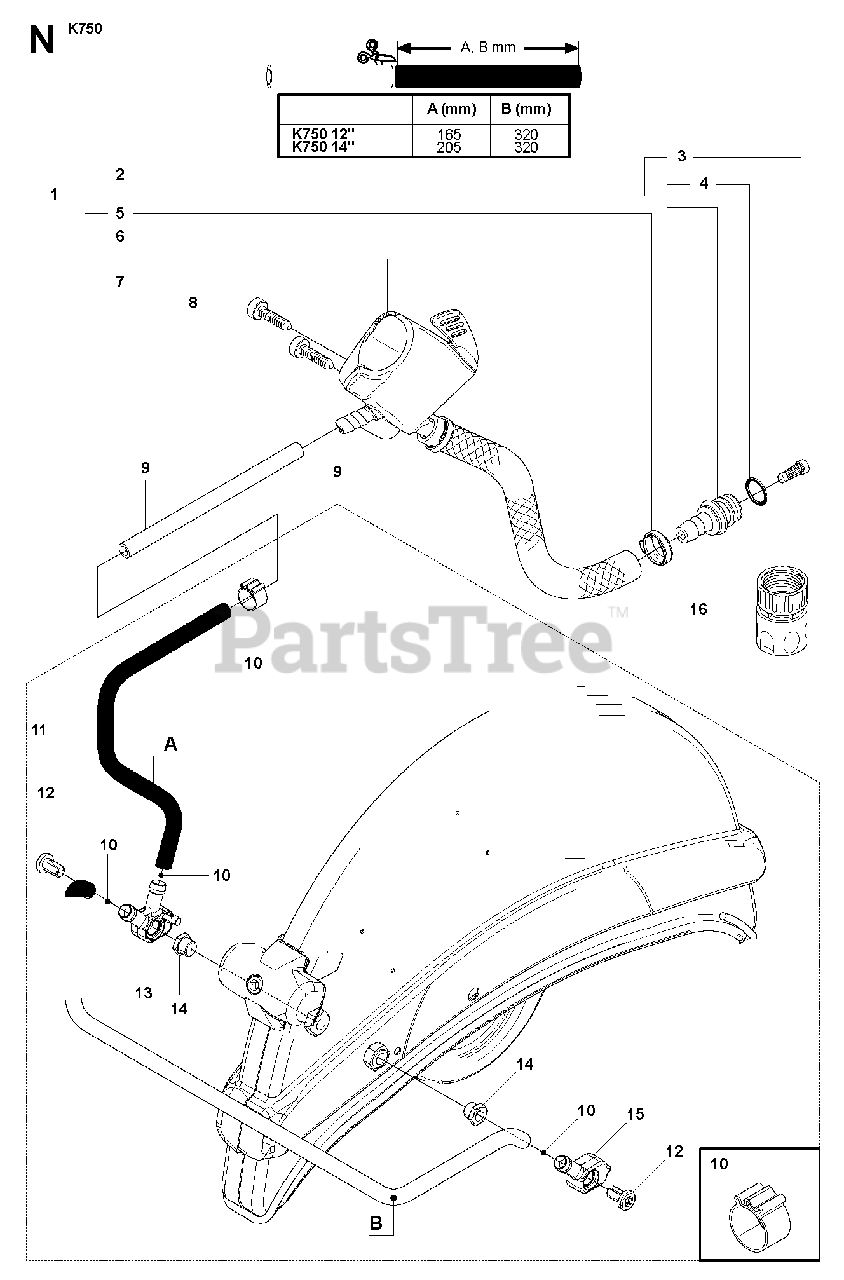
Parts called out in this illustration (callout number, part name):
1	HOSE KITIncl. 2, 5 - 7
2	NIPPLEIncl. 3, 4
4	HOSE CLAMP
5	HOSE CLAMP
8	SCREW ITXSCT
9	HOSE KITIncl. 10 - 15
11	HOSE320 mm
12	SCREW ITXSCM
